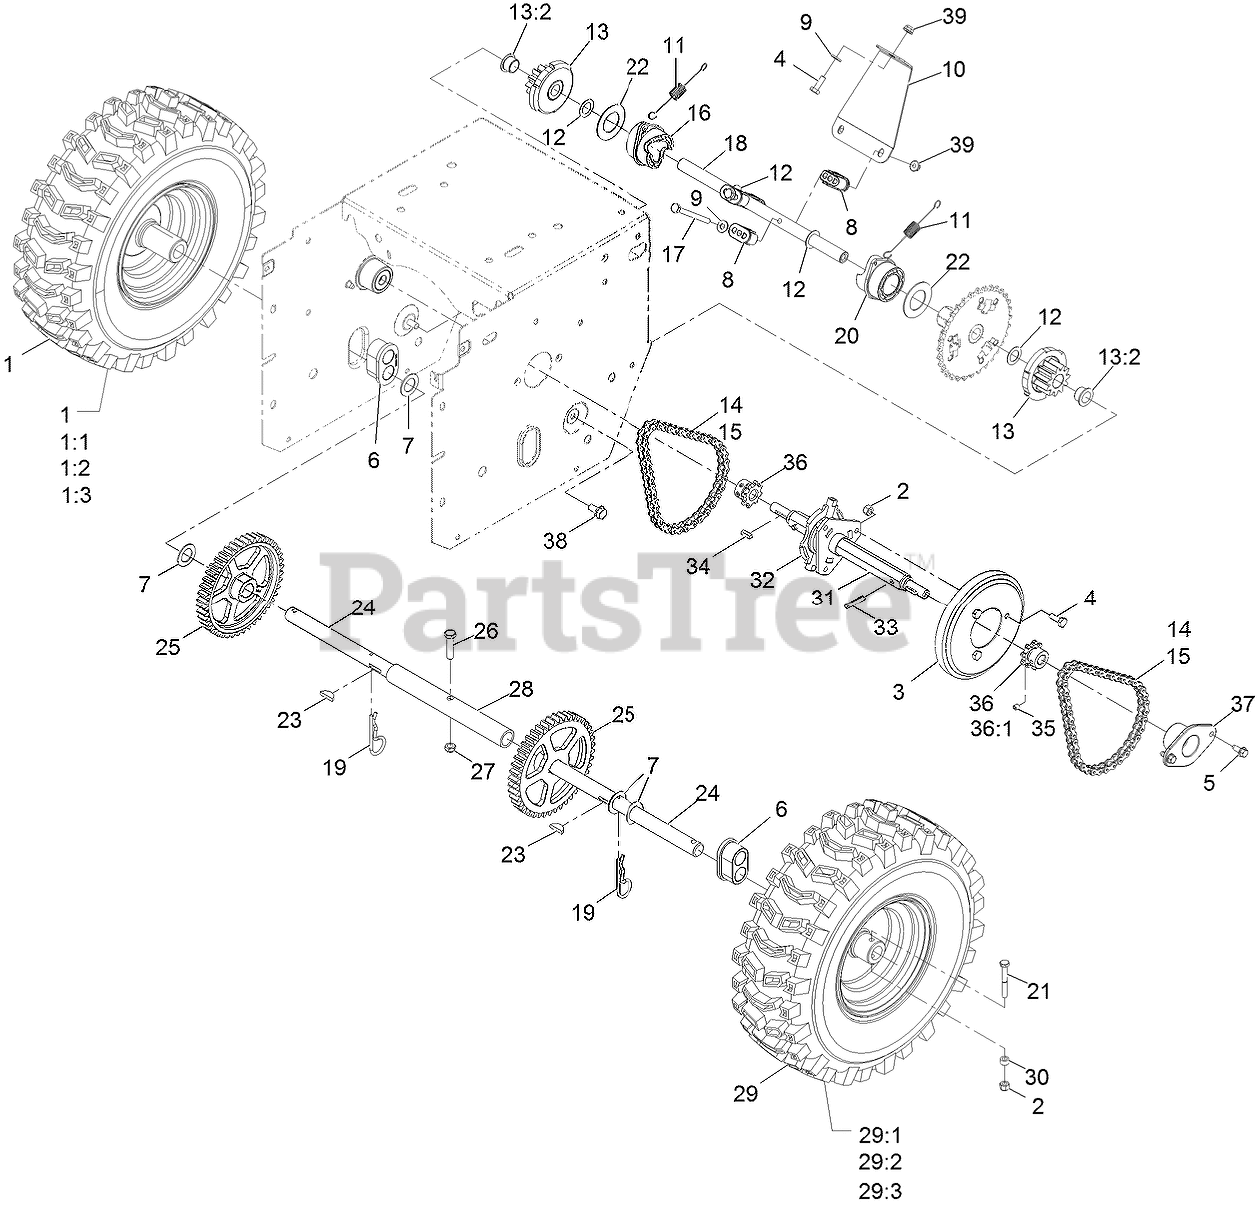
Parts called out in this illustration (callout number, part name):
1	RH Wheel And Tire ASM
1:2	RIM-TIRE
1:3	Stem-Valve
2	NUT-LOCK, NI
3	WHEEL-FRICTION
4	SCREW-HH
5	SCREW-HWH
6	BEARING-AXLE
7	WASHER-THRUST
8	GUIDE-COLLAR
9	WASHER-FLAT
10	BRACE-COLLAR, SHIFT
11	SPRING-EXTENSION
12	WASHER-FLAT
13	11T GEAR ASM
13:2	BUSHING-FLANGE
14	CHAIN-ROLLER
15	LINK-CONNECTING
16	COLLAR-SHIFT, RH
17	SCREW-HH
18	SHAFT-INTERMEDIATE
19	PIN-HAIR
20	COLLAR-SHIFT, LH
21	SCREW-HH
22	WASHER-THRUST
23	KEY-WOODRUFF
24	SHAFT-AXLE
25	GEAR-AXLE, 44 TOOTH
26	SCREW-HH
27	NUT-LOCK, NI
28	TUBE-AXLE
29	LH Wheel And Tire ASM
29:2	RIM-TIRE
29:3	Stem-Valve
30	SPACER-BLADE, ROTOR
31	SHAFT-HEX
32	TRUNNION-HEX
33	PIN-ROLL, SLOTTED
34	KEY-SQUARE
35	SCREW-HSH
36	SPROCKET-8 TOOTH
36:1	SCREW-HSH
37	RETAINER-BEARING
38	SCREW-HWHTF
